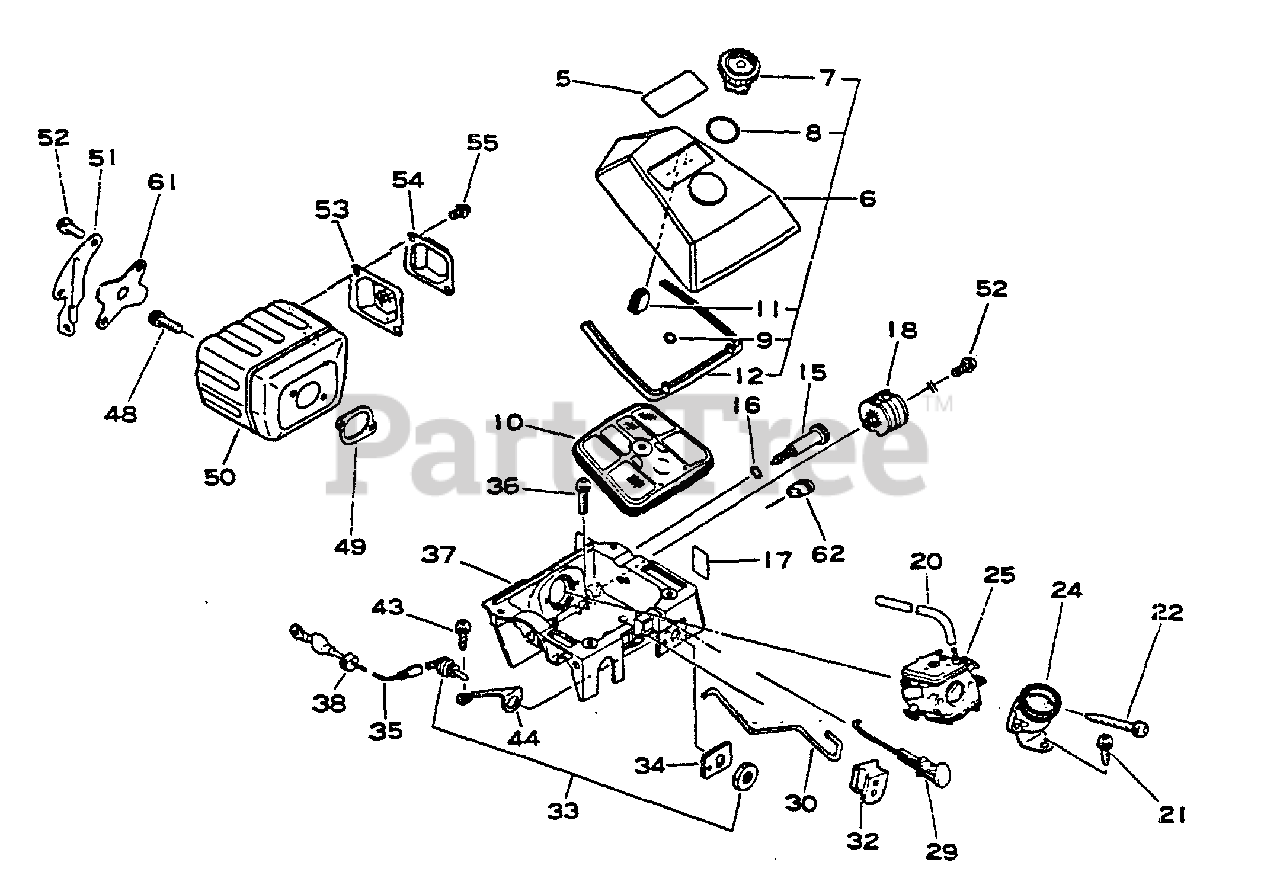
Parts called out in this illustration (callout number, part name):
5	LABEL
6	COVER ASSY, AIR FILTER
7	THUMBSCREW
8	O-RING 22
9	O-RING 10
10	FILTER ASSY, AIR
12	GASKET, AIR FILTER
15	SCREW, IDLE ADJUST - ORANGE
16	O-RING 7 MM
17	LABEL, CAUTION - IDLE
18	CUSHION
20	FUEL PIPE KIT
21	SCREW - 5×14
22	SCREW 5×53
24	ADAPTOR, INTAKE
25	CARBURETOR
29	ROD, CHOKE
30	ROD, THROTTLE
32	GROMMET, THROTTLE ROD
33	SWITCH, ON-OFF
34	LABEL, STOP
35	LEAD - GROUND
36	BOLT 5×20
37	CASE, CARBURETOR
43	BOLT 5×20
44	PLATE, GROUND
48	SCREW - 5×20
49	GASKET, EXHAUST
50	MUFFLER
51	BRACKET, MUFFLER
52	SCREW - 5×14
53	SCREEN, SPARK ARRESTER
54	OUTLET, EXHAUST
55	SCREW 4×10
61	COVER, MUFFLER
